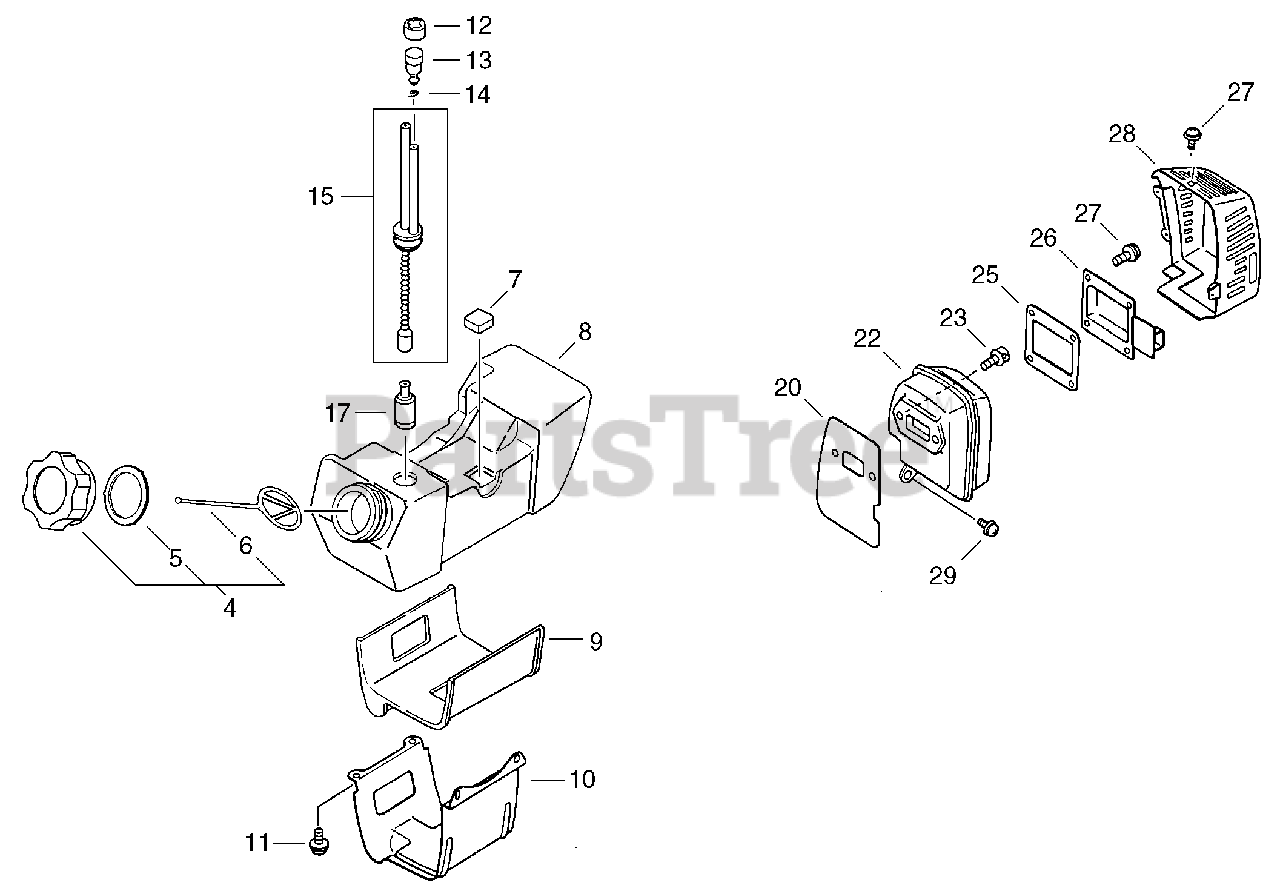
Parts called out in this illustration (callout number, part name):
4	CAP ASSY, FUEL
5	GASKET, FUEL CAP
6	CONNECTOR, CAP L= 100 MM
8	TANK, FUEL
10	BRACKET, FUEL TANK
11	SCREW 5×14
12	HOLDER, VENT
13	VENT ASSY
14	CLIP Ø6.5 MM
15	PIPE, FUEL
17	FILTER, FUEL
20	GASKET, MUFFLER
23	BOLT 5×20
25	GASKET, EXHAUST
26	GUIDE, EXHAUST
27	SCREW 4×10
28	COVER, MUFFLER
29	SCREW 5×14
